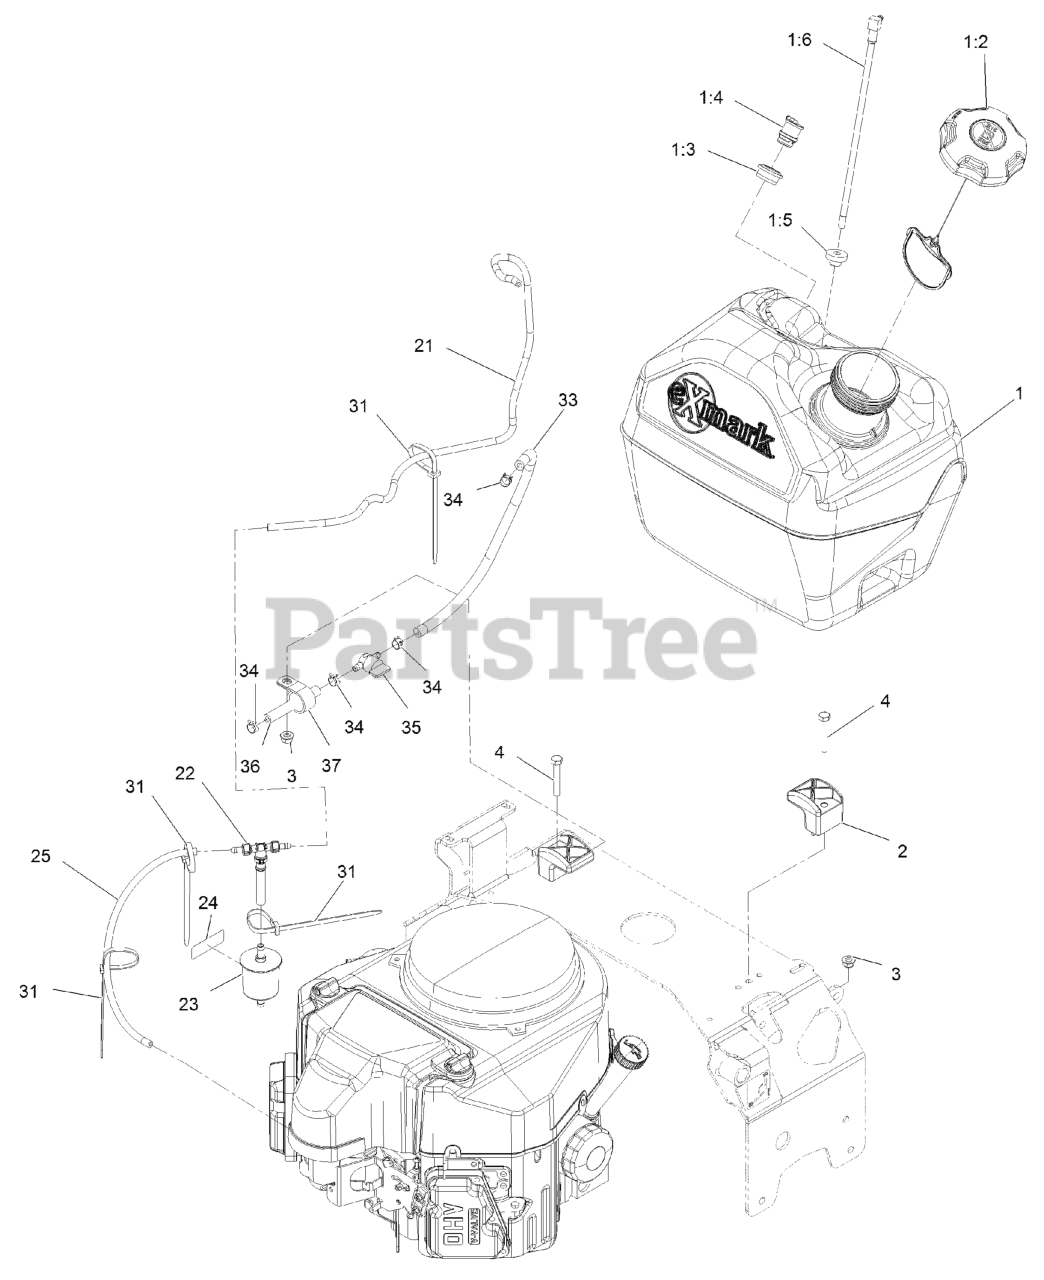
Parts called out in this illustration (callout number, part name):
1	ASM, FUEL TANK 5 GAL
1:2	CAP-FUEL, RATCHETING
1:3	GROMMET
1:4	VALVE-VENT, FUEL
1:5	BUSHING
1:6	FITTING, FUEL W/LINE AND SCREEN
3	NUT-HF, NI
4	SCREW-HH
21	HOSE, EMISSIONS
22	TEE AND CHECK
23	FILTER-FUEL
24	DECAL-FILTER, EMISSIONS
25	HOSE-FUEL
31	TIE-PLASTIC
33	HOSE-FUEL
34	CLAMP-HOSE
35	VALVE-FUEL
36	HOSE-FUEL
37	CLIP-LOOM
